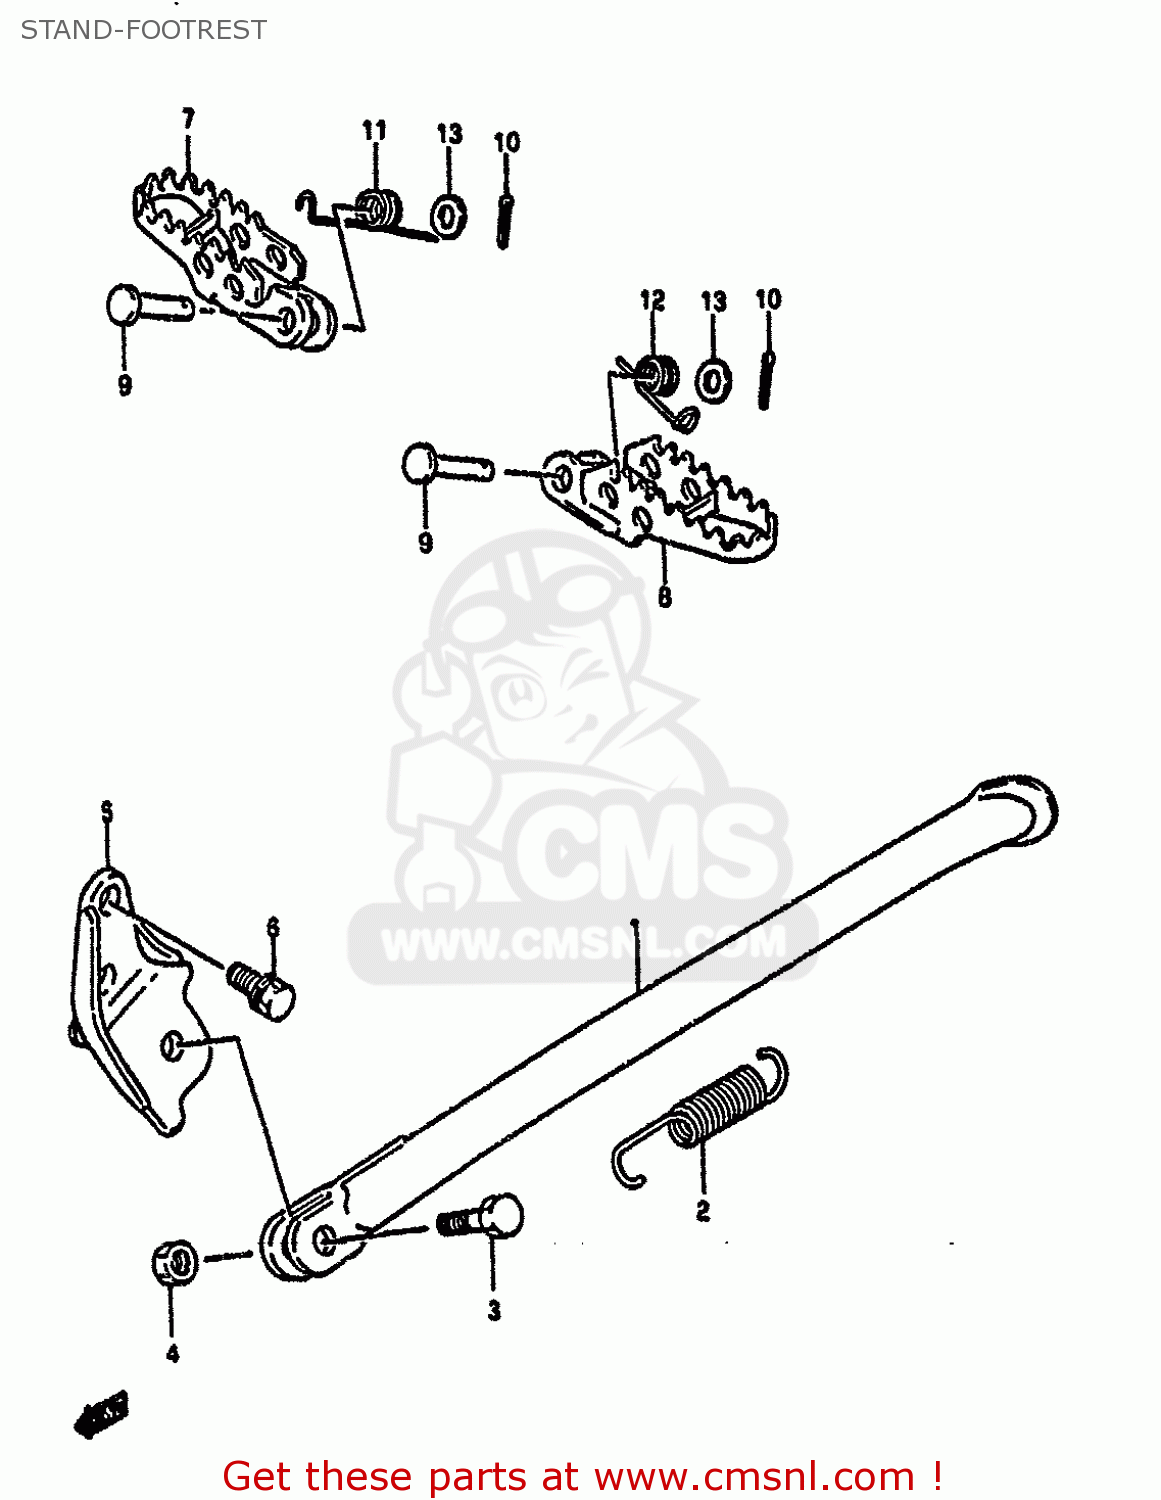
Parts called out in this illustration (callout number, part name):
1	STAND,SIDE
2	SPRING
3	BOLT(10X30)
4	NUT
5	BRACKET,SIDE STAND
6	BOLT
7	FOOTREST,FRONT,RIGHT
8	FOOTREST
9	PIN
10	PIN 25X20
11	SPRING
12	SPRING
13	WASHER
